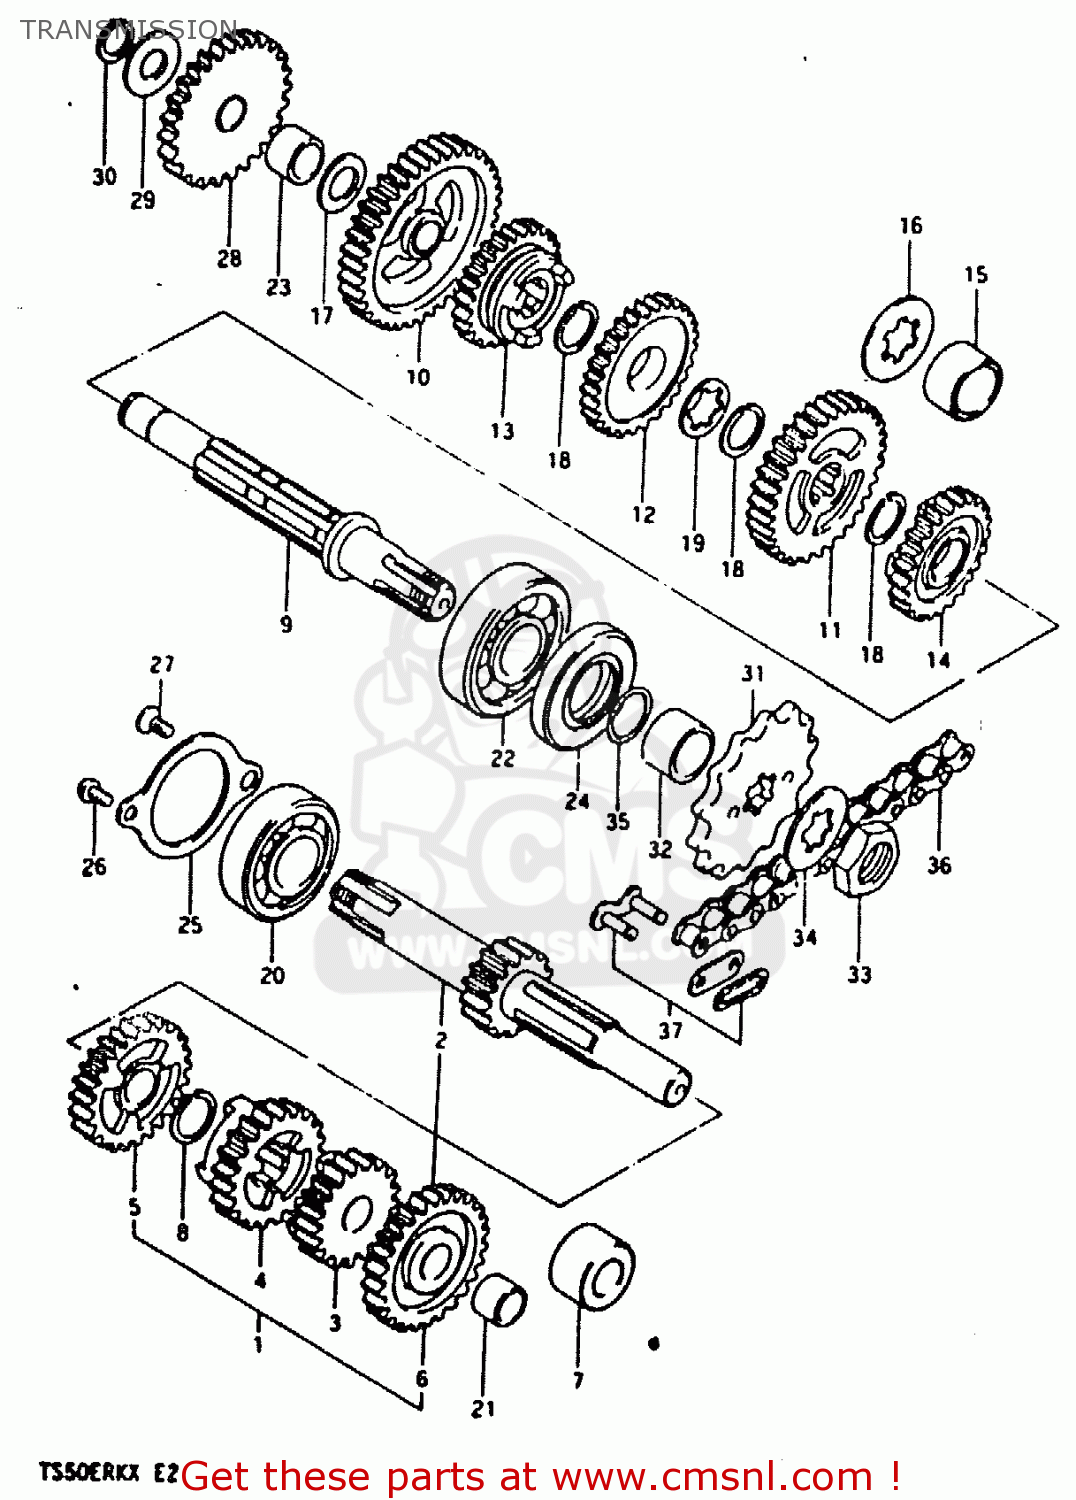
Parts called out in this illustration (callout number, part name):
1	SHAFT,COUNTER
2	SHAFT,COUNTER(NT:12)
3	GEAR,SECOND DRIVE
4	GEAR,THIRD DRIVE
5	GEAR,4TH DRIVE(NT:24)
6	GEAR,FIFTH DRIVE
8	CIRCLIP
9	SHAFT,DRIVE
10	GEAR,FIRST DRIVEN
11	GEAR,2ND DRIVEN(NT:33)
12	GEAR,3RD DRIVEN(NT:29)
13	GEAR,FOURTH DRIVEN
14	GEAR,5TH DRIVEN(NT:24)
17	WASHER(13X24X1)
18	CIRCLIP
19	WASHER,LOCK
20	BEARING
21	BUSH
22	BEARING
23	BUSH
24	SEAL,OIL(21X40X6)
25	RETAINER,CNTR SHAFT BEARING
26	SCREW
27	SCREW
28	GEAR,KICK STARTER IDLE
29	WASHER
30	CIRCLIP
31	SPROCKET,ENGINE(NT:12)
32	SPACER(17X21X13)
33	NUT
34	WASHER,LOCK
35	O RING(D:1,ID:16.8)
36	CHAIN, DRIVE (420*114L)
37	JOINT ASSEMBLY,CHAIN
